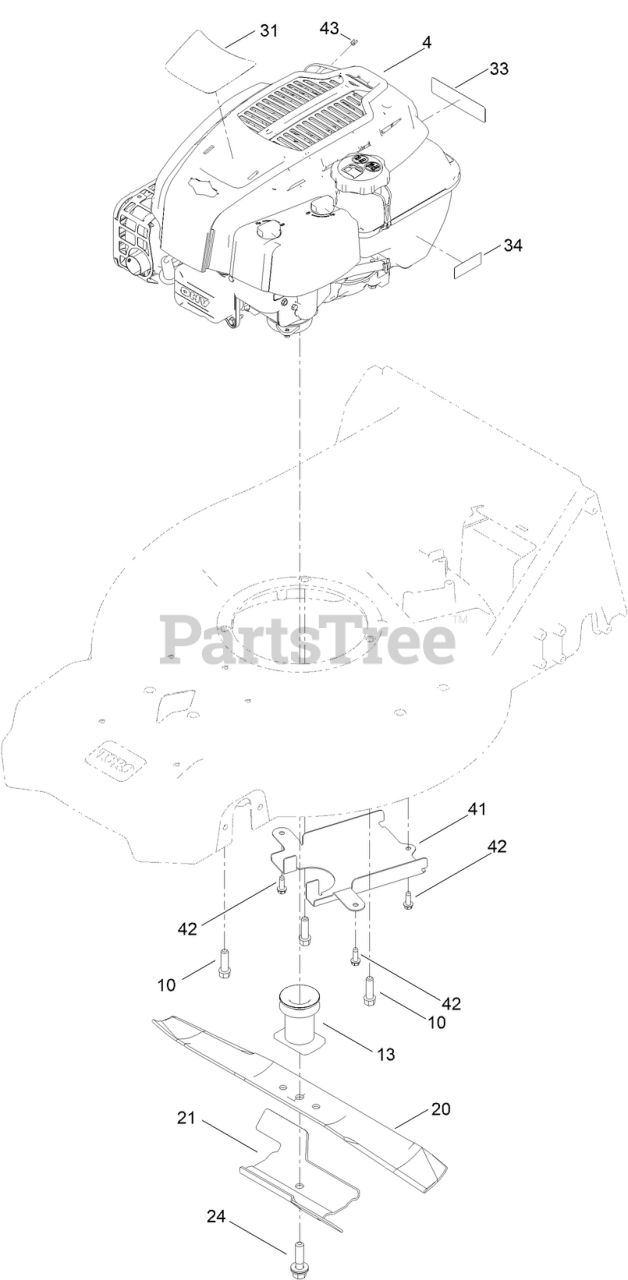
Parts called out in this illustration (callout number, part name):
4	ENGINE-BRIGGS 875 ES SS
10	SCREW-TAPTITE
13	DRIVER-BLADE
20	BLADE-21IN, RECYCLING
21	ACCELERATOR-BLADE
24	BOLT-BLADE
31	DECAL-BRIGGS 875 EXI
33	DECAL-ARRESTOR, SPARK
34	DECAL-LEVEL, FUEL
41	COVER-BELT, BOTTOM
42	SCREW-HWHTF
43	STOP-ROPE
